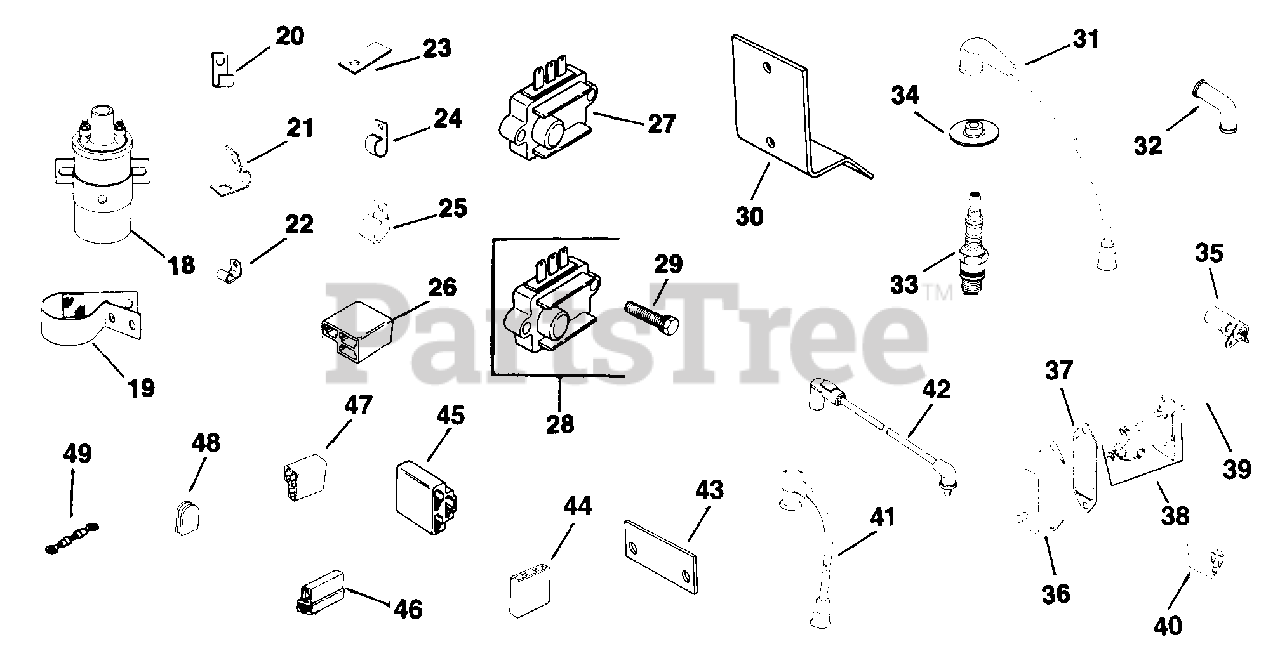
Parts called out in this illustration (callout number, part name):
27	REGULATOR
30	BRACKET - DISCONTINUED
32	BOOT - (#DSC)
33	SPARK PLUG USE 25 132 10-S
35	CONDENSER
37	GASKET, POINT COVER
44	CONNECTOR, BODY (KM)-USE 25 155 41-S
48	GROMMET
